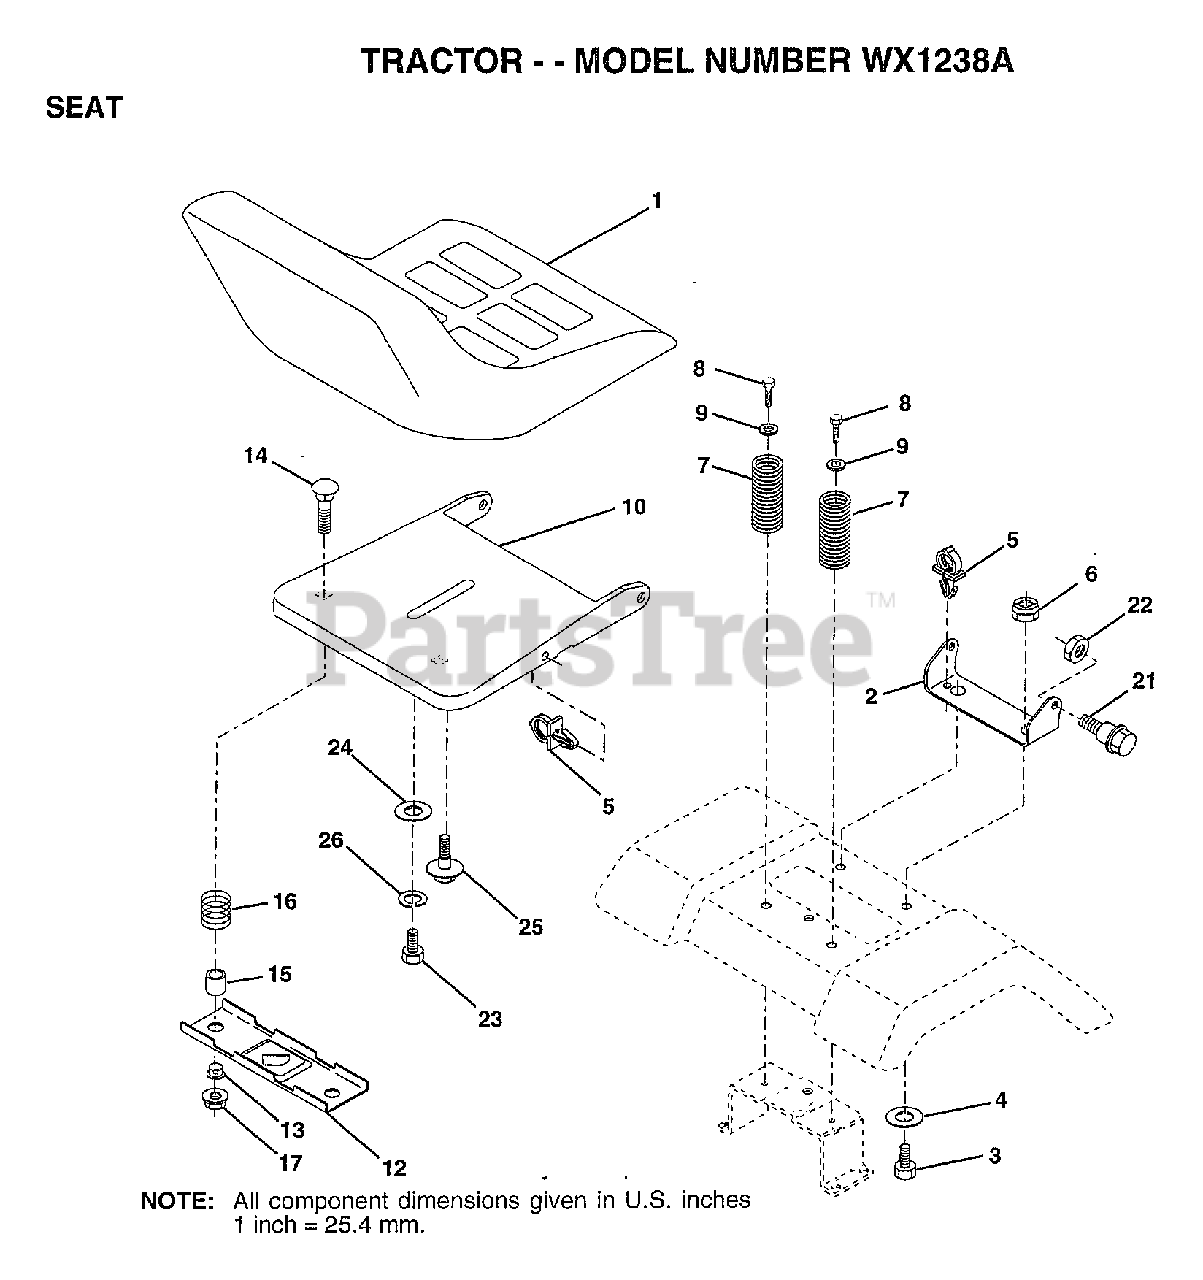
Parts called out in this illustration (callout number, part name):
2	BRACKET PVT SEAT
3	BOLT
4	WASHER PM
5	CLIP.PUSH-IN.HING
6	NUT
7	SPRING COMPRESSIO
8	SCREW GTV
9	WASHER
12	BRKT SWITCH
13	BUSHING
15	SPLIT SPACER
16	SPRING
21	BOLT.SHLD.5/16-18
22	NUT
23	BOLT
24	WASHER
25	"BOLT,SHOULDER"
26	LOCKWASHER
